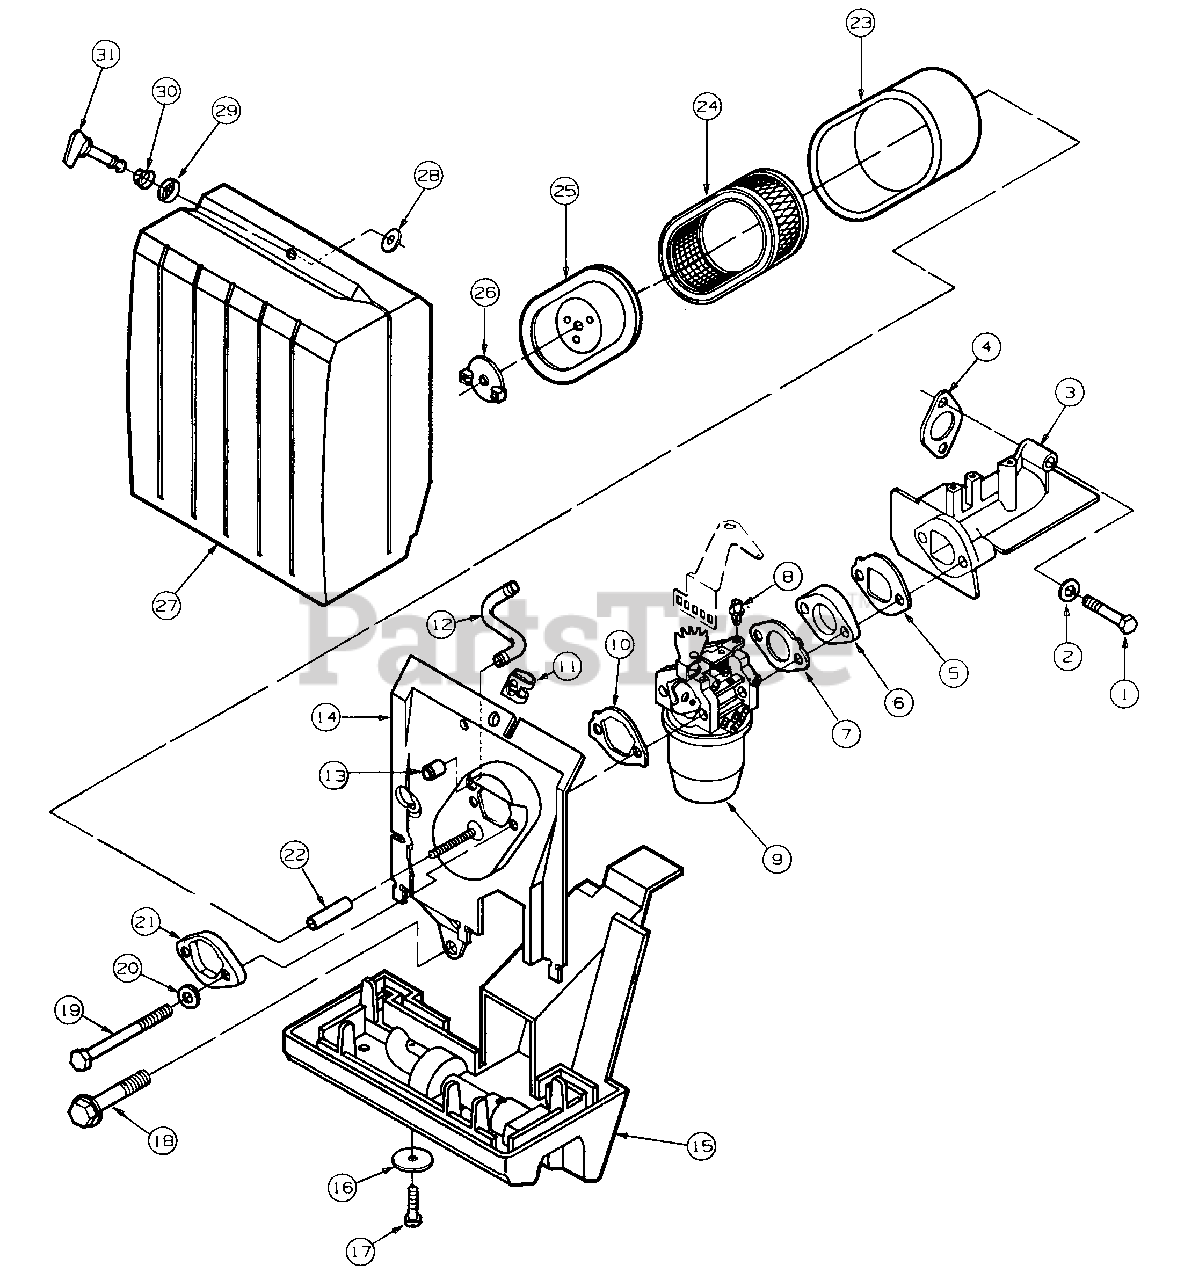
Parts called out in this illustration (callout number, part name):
1	Screw, Hex Head Cap M8 x 1.25 x 50 mm
2	Washer, Flat, M8
3	Elbow, Intake
4	Gasket, Intake
5	Gasket, Insulator
6	Insulator, Carburetor
7	Gasket, Insulator
9	Carburetor
10	Gasket, Air Cleaner
11	Receptacle, Fastener
12	Tube, Breather
14	Pan Assy, Air Cleaner
15	Duct, Air Inlet
16	Washer, Fender (Special)
17	Screw, Pan Head, Thread Forming, #10-16 x 1/2
18	Screw, Hex Head Flange, Thread Forming, M8 x 1.25 x 16 mm
19	Screw, Hex Head, Thread Forming, M6 x 1 x 90 mm
20	Washer, Flat, M6
21	Support, Carburetor
22	Seal, Air Cleaner Spacer .625
23	Wrapper, Air Filter
24	Filter, Air
25	Cover, Air Filter
26	Nut, Wing, 1/4-20
27	Cover, Air Cleaner
28	Washer, Nylon (Special)
31	Fastener, 1/4 Turn
